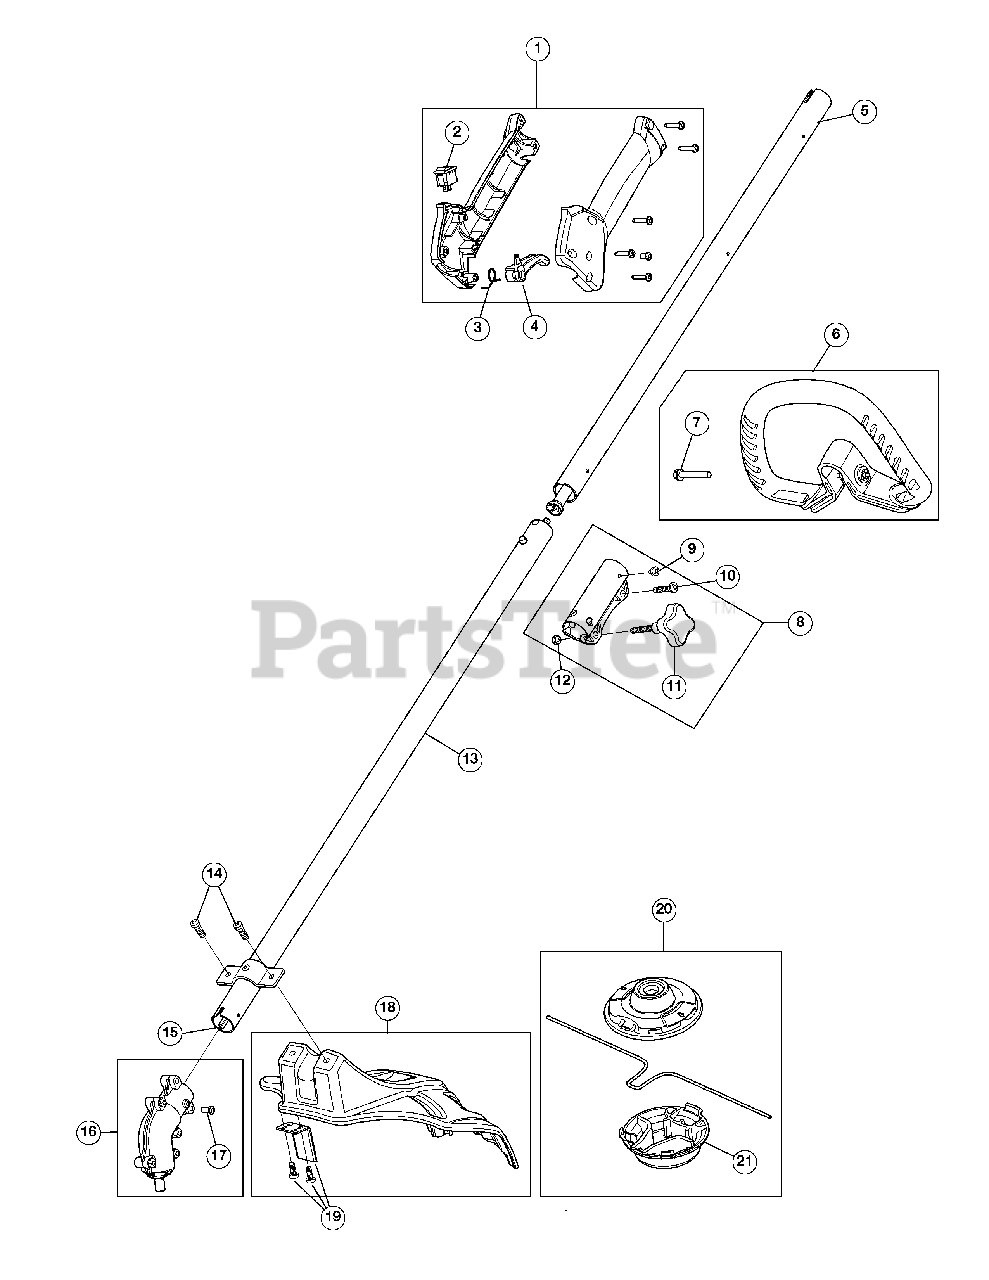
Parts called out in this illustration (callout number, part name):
1	Throttle Housing Assembly (Incl. 2 - 4)
3	Throttle Trigger Spring
4	Throttle Trigger
5	Upper Shaft Housing Assembly
6	D-Handle (Incl. 7)
7	D-Handle Bolt
8	Split Boom Coupler (Incl. 9 - 12)
9	Coupler Anti-Rotation Screw
11	Adjustment Knob
12	Knob Retainer Nut
13	Lower Shaft Housing Assembly
14	Shield Mounting Screws
15	Lower Flexible Drive Shaft
16	Gear Box Assembly (Incl. 17, 20 & 21)
17	Anti-Rotation Screw
18	Shield Assembly (Incl. 14 & 19)
19	Blade Assembly
20	Cutting Head Assembly (Incl. 21)
21	Glide Cap
